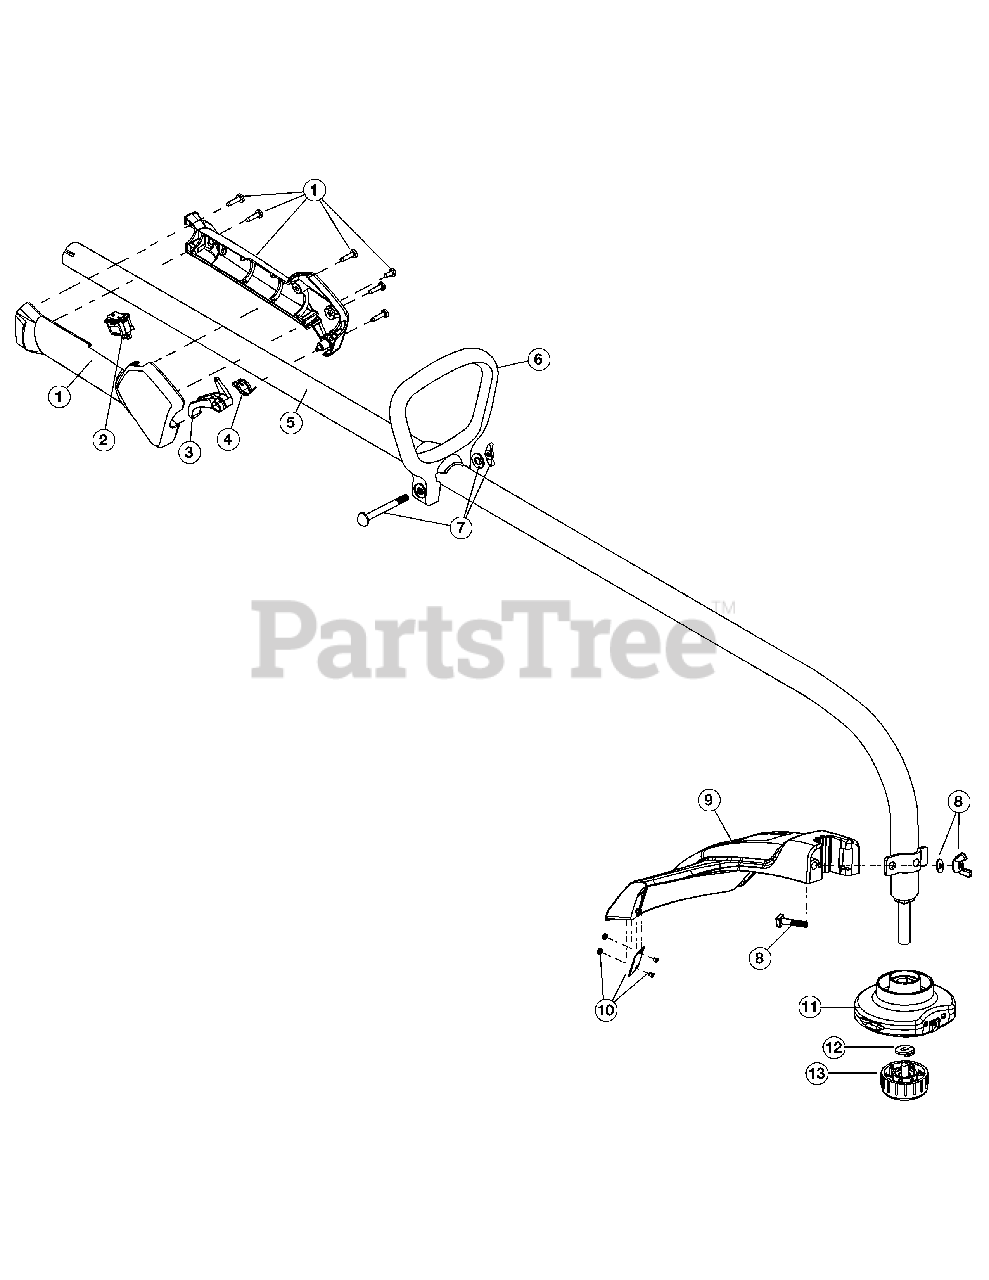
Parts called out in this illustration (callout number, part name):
1	Throttle Housing Assembly (includes 2-4)
3	Throttle Trigger
4	Throttle Trigger Spring
5	Drive Shaft Housing Assembly
6	D-Handle (includes 7)
7	Handle Hardware
8	Guard Mounting Hardware
9	Guard (includes 10)
10	Blade Assembly
11	Fixed Line Head
12	Lock Washer
13	Bump Head Knob Assembly
